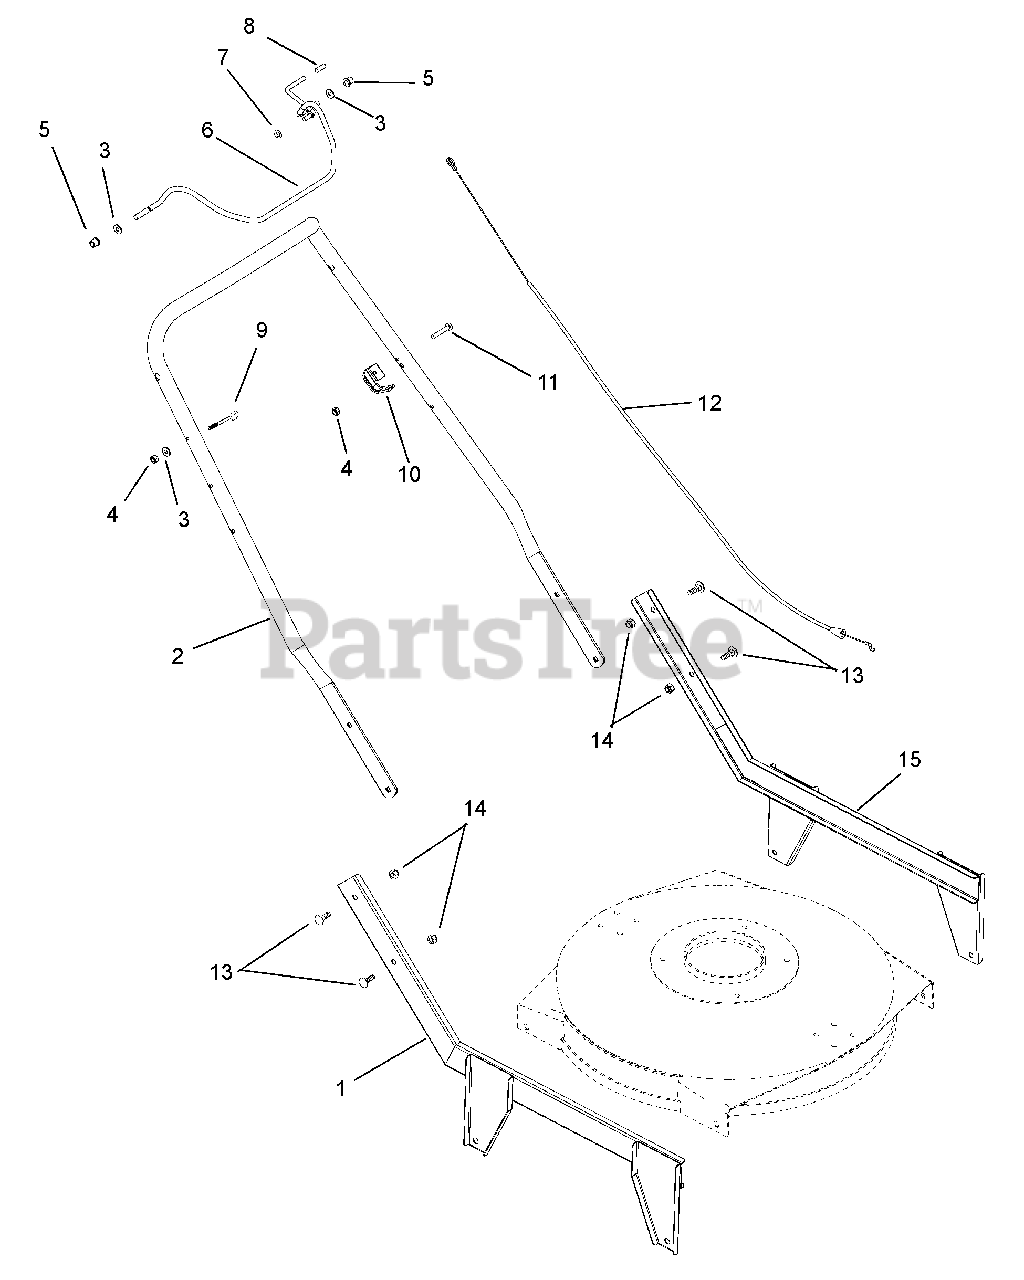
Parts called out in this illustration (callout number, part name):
1	Weldment, Handle Mount, Right Side
2	Handlebar, Modified
3	Washer, Flat .25
4	Hex Nut, .25-20
5	Bushing, Flange
6	Weldment, Engine Bail
7	Ring, External Retaining
8	Cap, Vinyl .25 ID
10	Bracket, Engine Cable Anchor
11	Capscrew, Hexhead .25-20 x 1.5
12	Cable, Engine Control
13	Bolt, Roundhead Squareneck .313-18 x .5
14	Nut, Hex Nylock .3125-18
15	Weldment, Handle Mount, Left Side
